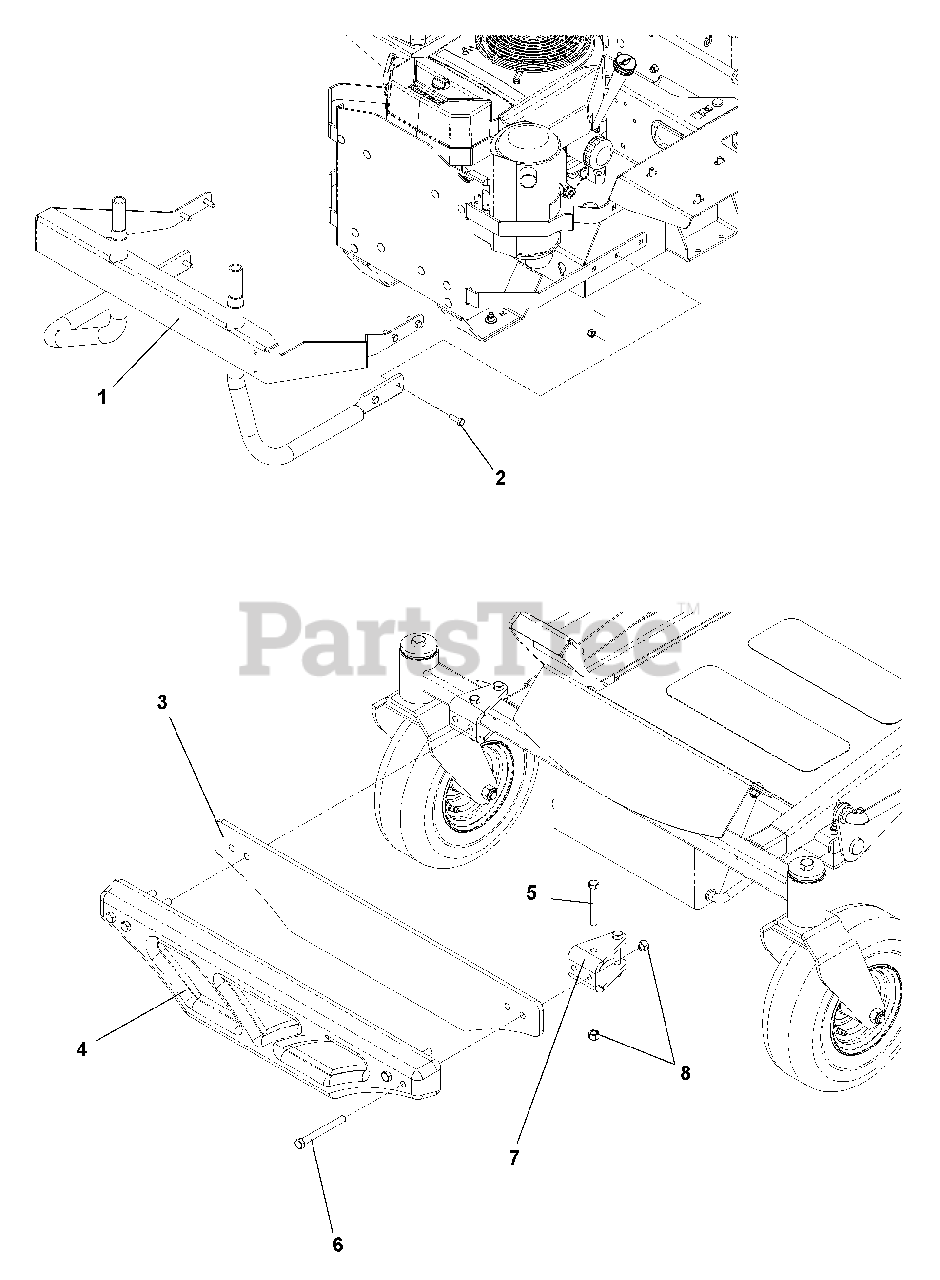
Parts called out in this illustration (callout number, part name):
1	Catcher Hitch
2	HCS, 5/16-18 x 1, Gr5
3	Weight Plate
4	Cast Weight
5	HCS, 3/8-16 x 2 3/4, Gr5
6	HCS, 3/8-16 x 3 1/2, Gr5
7	Weight Bracket
8	Nut, 3/8-16, Nyloc
